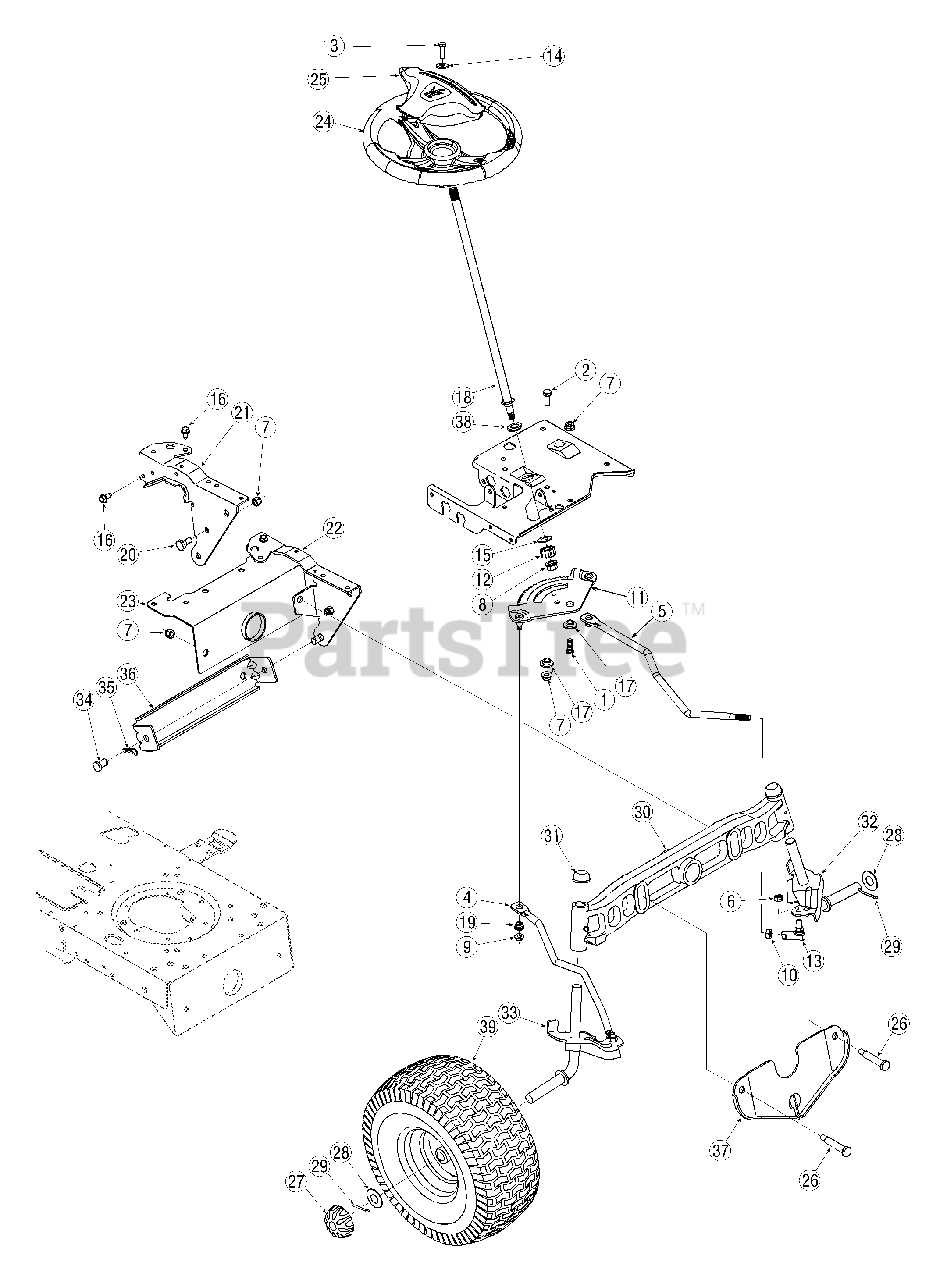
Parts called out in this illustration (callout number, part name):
1	Hex Screw, 3/8-16, 1.00, Gr5
2	Hex Screw, 3/8-16, 1.00, Gr5
3	Hex Screw, 5/16-18, 1.00, Gr5
4	Link, Drag, RH
5	Link, Drag, LH
6	Nut, Hex Lock, 3/8-24
7	Nut, Flange Lock, 3/8-16, Grf, Nylon
8	Nut, Flange Lock, 7/16-20
9	Nut, Flange Lock, 5/16-18, Gr5
10	Nut, Jam, 7/16-20, Gr2
11	Gear, Steering, 11/90 Ratio
12	Gear, Pinion, Steering
13	Ball Joint, 7/16-20, Lock
14	Washer, Flat,.406 x.875 x.105
15	Washer, Flat,.51 x 1.12 x.06
16	Screw, 5/16-12, 0.750
17	Spacer, Shoulder,.38 x 1.00 x.31
18	Shaft, Steering,.625 OD x 24.25 Lg
19	Plastic Bushing.380 ID
20	Screw, Shoulder,.498 x.340, 3/8-16
24	Steering Wheel, 3 Spoke, Soft Grip
25	Steering Wheel Cover
26	Shlder Screw,.5 x 2.380, 3/8-16 LT942H)
26	Shlder Screw,.5 x 2.2, 3/8-16 LT946H)
27	Deluxe Hub Cap
28	Flat Washer,.78 x 1.589 x.06
29	Cotter Pin, 5/32 x 1.25
30	Cast Iron Pivot Bar
32	LH Axle Assembly,.750 (LT942H)
32	LH Axle Assembly,.750 (LT946H)
33	RH Axle Assembly,.750 (LT942H)
33	RH Axle Assembly,.750 (LT946H)
34	Pin, Clevis,.50 x.78 (LT946H)
35	Cotter Pin, Inter,.080 x 1.5625 (LT946H)
38	Hex Flange Bearing
